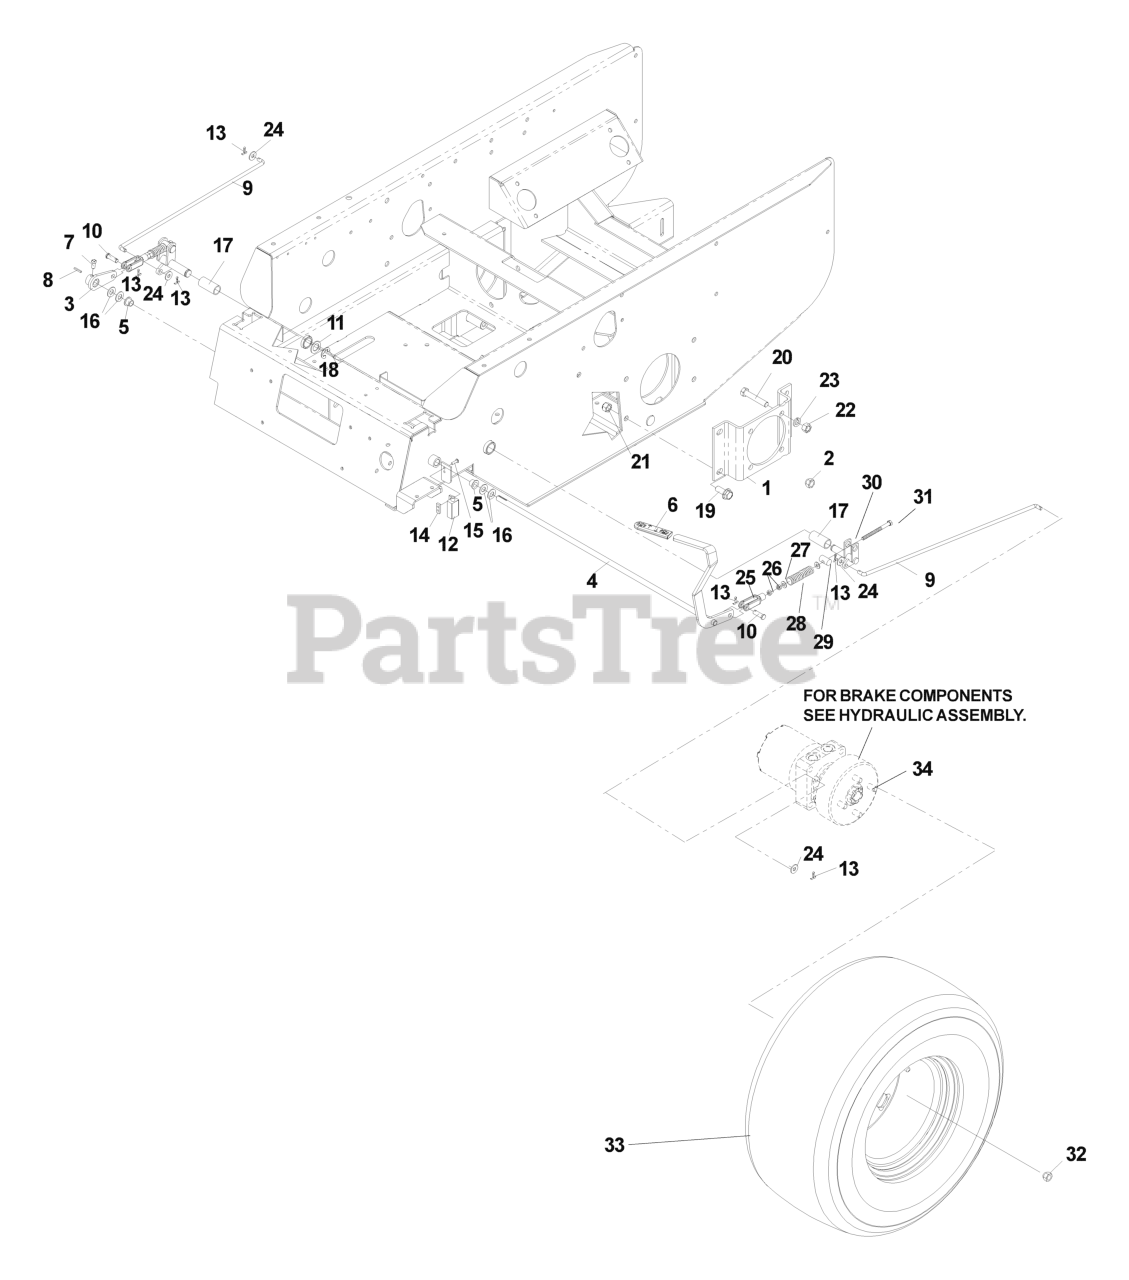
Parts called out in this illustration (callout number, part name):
1	MOTOR STANDOFF - PAINTED
2	LUG NUT 1/2F
3	BRAKE ARM WELDMENT
6	GRIP, PARK BRAKE
7	SCREW 5/16C X 5/8 SQ HEAD
9	BRAKE LINKAGE BAR
10	CLEVIS PIN 3/8 X 1 1/8
13	RP_COTTER PIN 1/8 X 3/4
14	TAPPED PLATE
15	SCREW #10-24 X 5/8
16	WASHER, 7/16 DISC SPRING
17	BRONZE BEARING
18	E RING 3/4
19	HCS 1/2C X 1 1/4 SERRATED HEAD
20	HCS 1/2C X 2 3/4
21	NUT 1/2-13 HEX NYLOC ZD
22	NUT HEX 1/2
23	WASHER 1/2" SPLIT LOCK
24	WASHER 5/16 FLAT
25	YOKE-3/8-24 PLTD
27	WASHER 3/8 SAE FLAT
29	TRUNION PIN
31	HCS 3/8F X SPECIAL
32	LUG NUT 1/2F
33	TIRE/WHEEL ASSY 26 X 12-12
33	TIRE, 26-12 X 12
33	12"RIM 2.5" NEG OFFSET 8.5" W
33	VALVE STEM TR-412
34	WHEEL STUD 1/2-20X1-3/8 GR8 ZN
